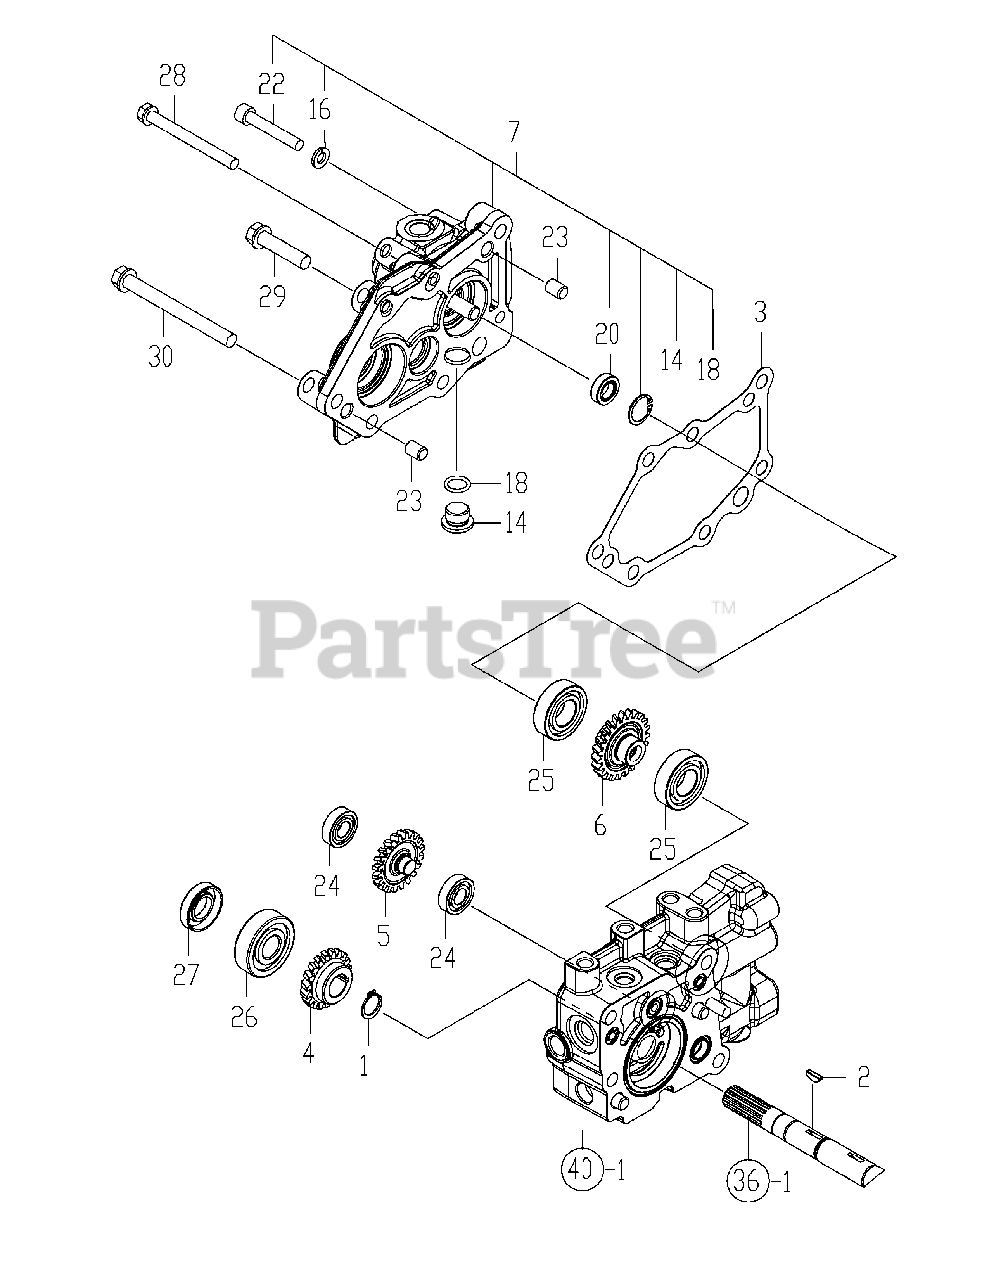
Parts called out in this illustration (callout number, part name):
2	KEY, 13X3.2
3	PAKING (PUMP COVER
7	PWS-5CG SUB CMP
18	PACKING, P 14.0
20	SEAL, TC122207
26	BEARING, 6303
27	SEAL, TC173508
30	BOLT, 10 X 105
